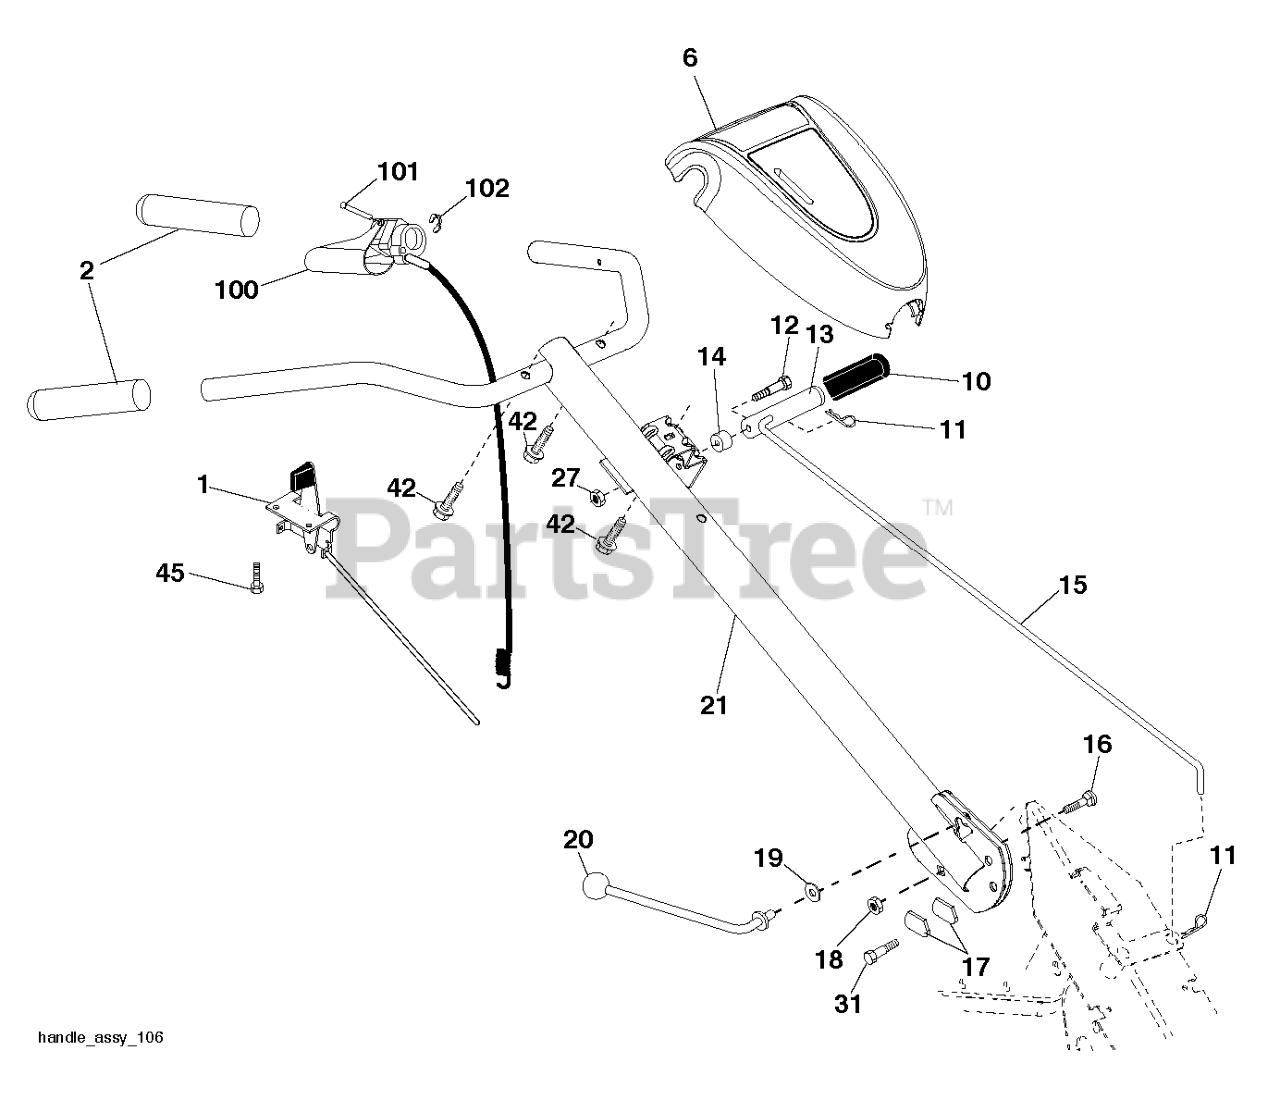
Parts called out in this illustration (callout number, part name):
1	CONTROL.THROTTLE.SNAP.IN
2	GRIP.1X5.06
6	CONSOLE.GREY.DRT.W.SLOT.DRT900
10	GRIP T
11	RETAINER M
12	SHOULDER BOLT ST
13	HANDLE
14	GROMMET.RUBBER.CRT.TILLER
15	ROD SHIFT RT UNIVERSAL
16	BOLT D
17	LOCK.HANDLE.CRT
19	WASHER CRT
20	LEVER.LOCK.CRT
21	HANDLE.ASM.HUSQ/P.PRO.GREY
27	NUT T
31	BOLT.PIVOT
42	SCREW.#10 X 0.750.BOS
45	SCREW.#10 X 0.500
100	CONTROL.ASSEMBLY.TINE.TILLER
101	PIN, PIVOT
102	RETAINING.RING.#5103-25
